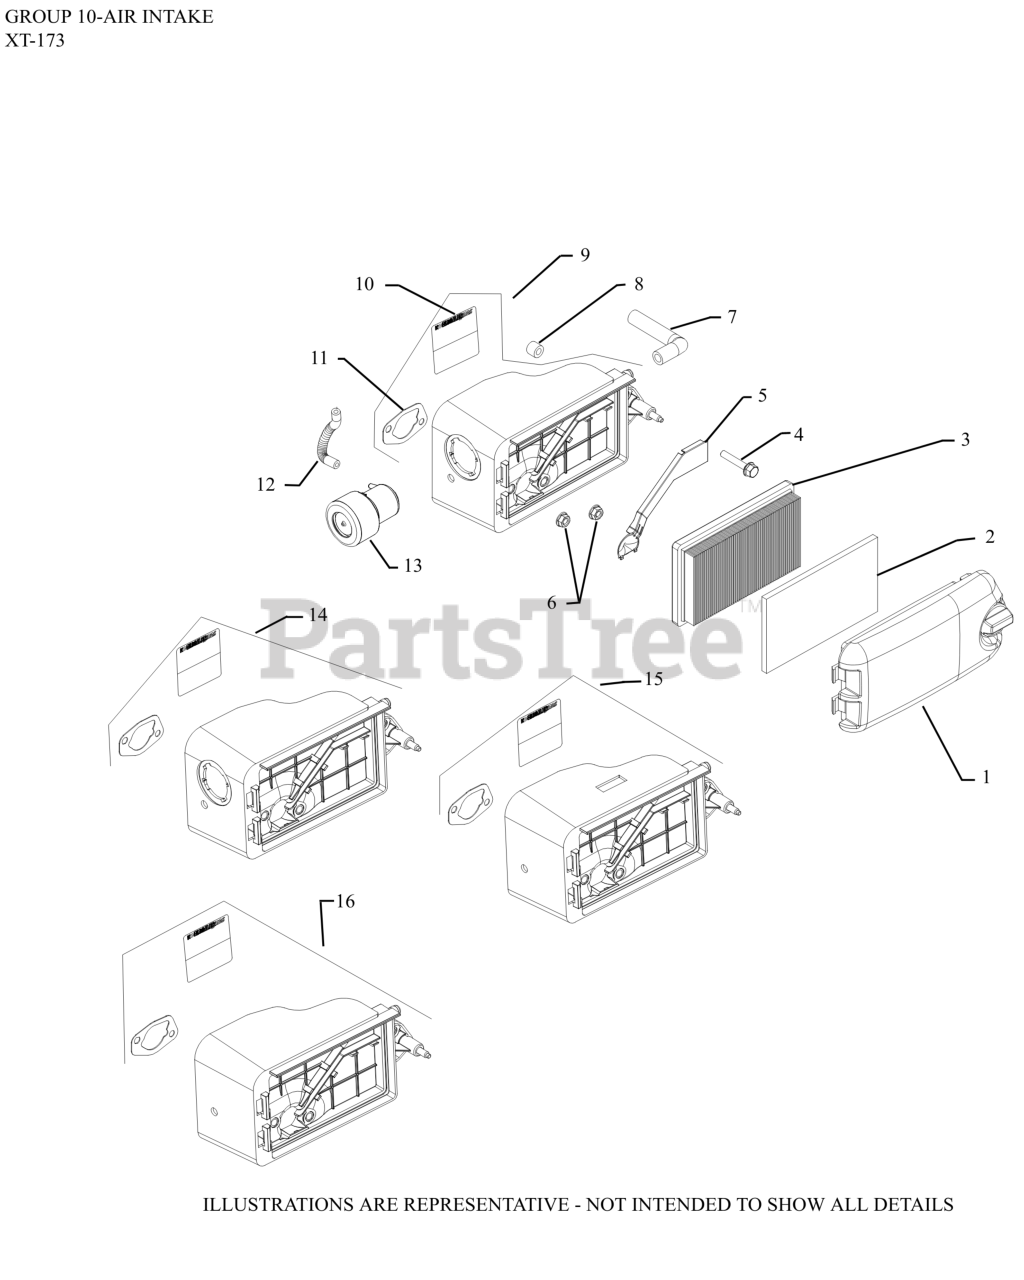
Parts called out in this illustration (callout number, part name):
1	KIT, AIR CLEANER COVER-USE 14 096 110-S
2	ELEMENT, PRE-CLEANER
3	ELEMENT, AIR CLEANER-(#1408319S)
5	COVER, A/C BASE (BREATHER GAS)
7	HOSE, BREATHER
9	KIT, AIR CLEANER BASE-USE 14 094 24-S
12	HOSE, PRIMER
13	KIT, PRIMER ASSY (EVAP)-DISC.SEE PB-264
NI	KNOB-USE 14 341 07-S
